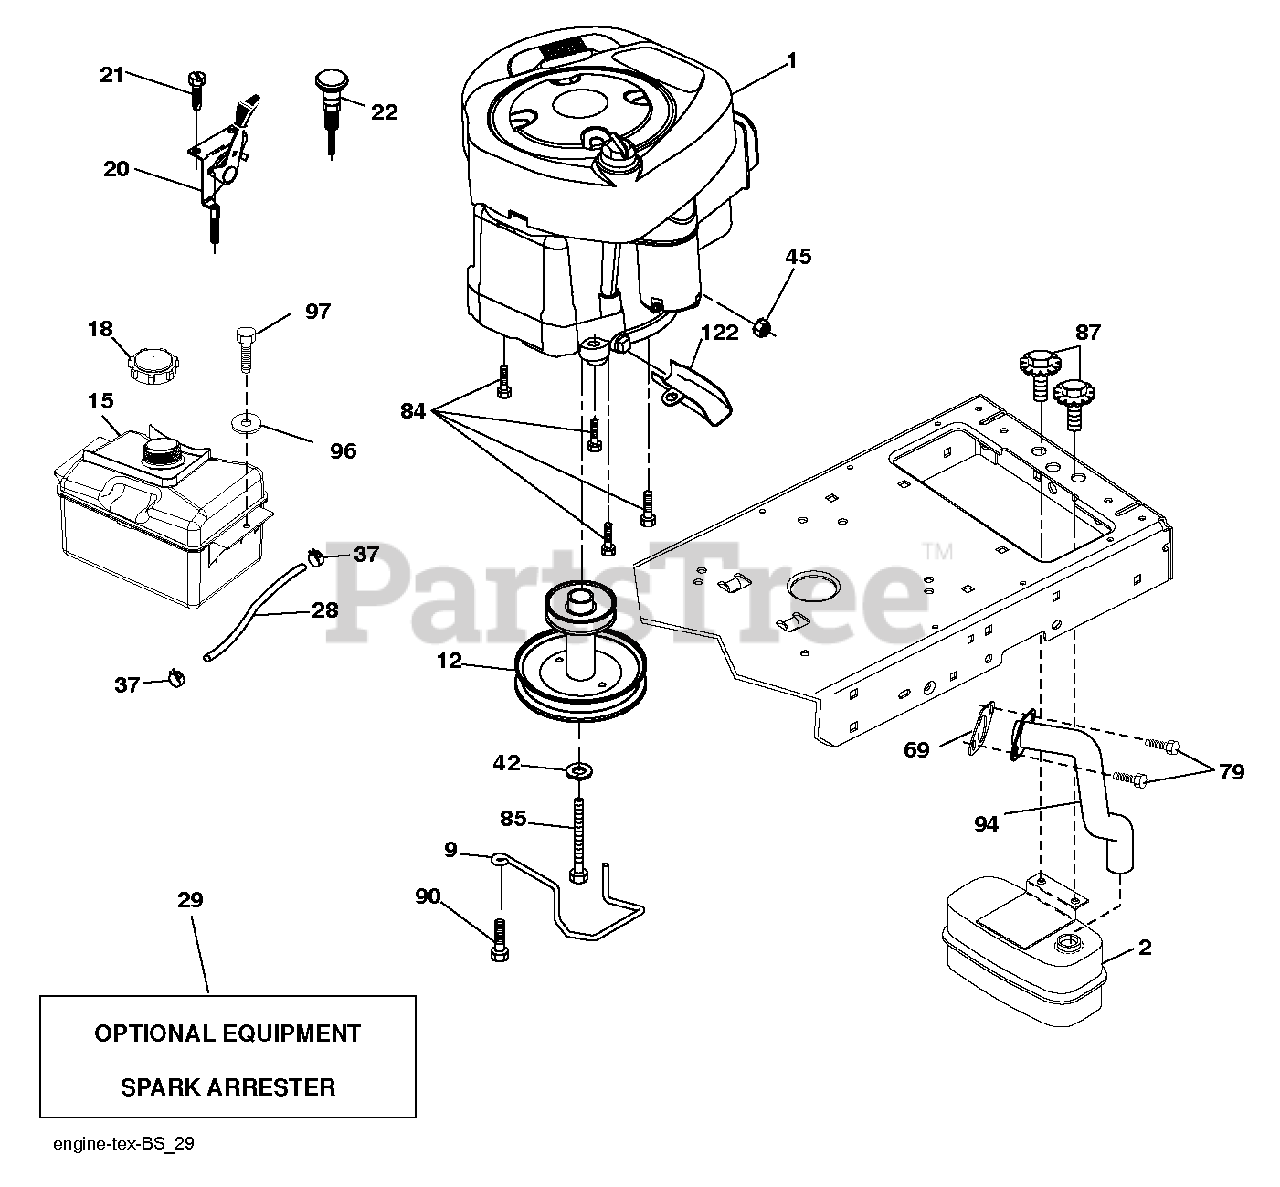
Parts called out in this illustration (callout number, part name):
2	MUFFLER.SINGLE.CYL.KOHL/B&S
9	KEEPER.BELT.ENGINE.3.25
12	PULLEY ENGINE
15	TANK FUEL FRT 1.5 GAL
18	CAP ASM.FUEL.2.25"FR.
20	CONTROL.TH/CK.C.
21	SCREW.#10 X 0.750.BOS THREAD
28	LINE.FUEL.20
29	ARRESTER SPARK (OPTIONAL)
37	HOSE CLAMP
42	LOCKWASHER
45	NUT
69	REPL BY 532 27 22-93
79	SCREW.SOCKET HD.5/16-1
84	SCREW.3/8-16
85	BOLT HEX 7/16-20X4-1/4"
87	BOLT, 5/16-18 X 1 3/4
90	SCREW 3/8-16X1
94	EXHAUST.TUBE.B&S.
97	SCREW HEXWSHR 1/4-20X3/4
122	EXTENSION DRAIN OIL
